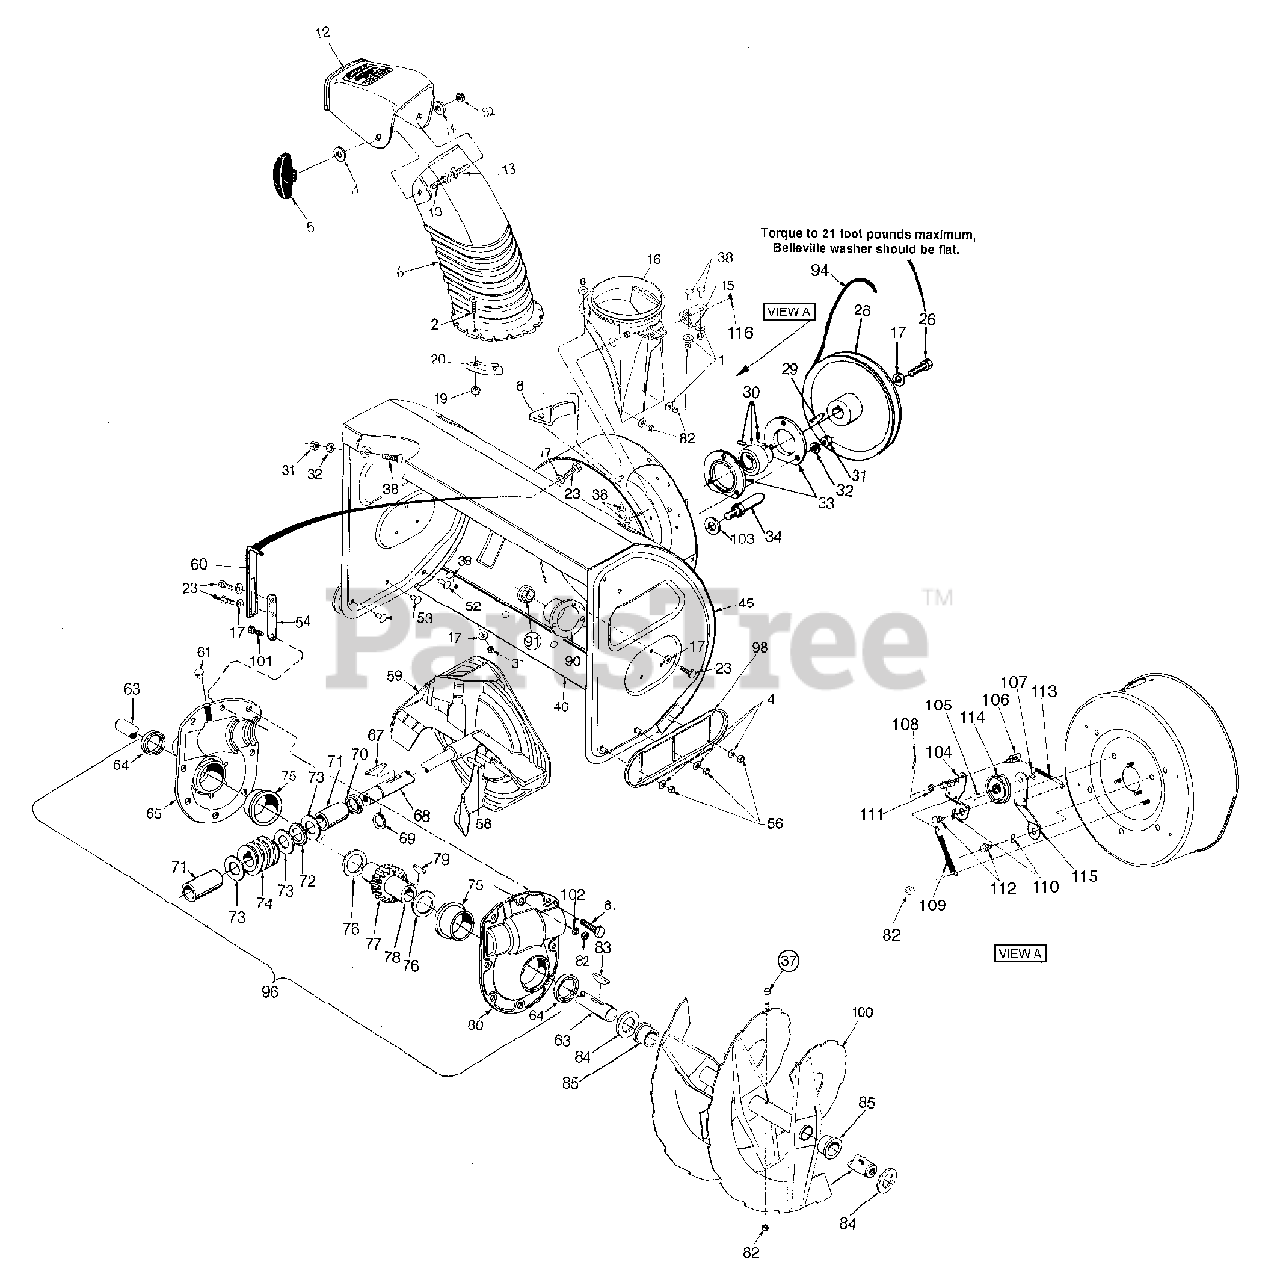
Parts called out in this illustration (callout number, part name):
1	Flat Washer .344 ID x .875 OD
2	Truss. Hd. Mach. Scr. 1/4-20 x .75
4	Belleville washer
5	Handle knob Ass'y
6	Extended lower black plastic chute 6" dia.
13	Carriage Bolt 5/16-18 x 1.00" Lg
14	Flat Washer .344 ID x .875 OD
16	Chute Adapter
17	Bell. Washer .345 ID x .88 OD x .06
19	Hex Cent. L-Nut 1/4-20 w/ Flange
20	Chute Flange Keeper
23	Hex Wash HD Self-Tap Scr 5.16-18 x .75
26	Hex Screw 5/16-18 x .75
28	1/2" V-Pulley .875 ID x 10.12 OD
29	#9 Hi-Pro Key 3/16 x 3/4 Dia HT
30	Self-Aligning Bearing .875 ID
31	Hex Nut 5.16-18 GD. 5
32	L-Wash 5.16 ID
33	Bearing Housing
34	Belt Keeper Studs 3/8-16 x 2.75
38	Carriage Bolt 5.16-18 x .75
52	Carriage Bolt 3/8-16 x 1.00 Gr. 5
53	Carriage Bolt 3/8-16 x .75" Lg.
56	Hex Jam Nut 3/8-16
58	Spring Spiral Pin Heavy - 5/16 dia x 1.7
61	Barbed Plug
63	Spiral Axle - 30"
64	Oil Seal 1.50 ID Garlock (76 x 6223)
65	Gear Housing Half - RH
67	#9 Hi-Pro Key 3/16 x 3/4 dia HT
68	Auger Drive Shaft
69	Snap Ring for .875 dia. shaft
70	Oil Seal for .875 ID Garlock (76 x 6133)
71	Sleeve Bearing .875 ID
72	Thrust Bearing .88 ID x 1.44 OD x .078
73	Flat Washer .88 ID x 1.4 OD x .125
74	Worm Gear LH Double Thread
75	Flange Brg. 1.5 ID x 1.75 OD x .80
76	Flat Washer 1.5 ID x 2.0 OD x .03
77	Worm Gear LH Double Thread (Bronze)
78	Worm Gear Shaft
79	#91 Woodruff Key 1/4 x 3/4 dia
80	Gear Housing Half LH
81	Hex Flange Scr. 5/16-18 x .75
82	Hex Ins. L-Nut 5/16-18
83	#91 Woodruff Key 1/4 x 3/4 dia
84	Flat Washer
85	Flange Bearing
91	Flange Bearing w/flats
94	V-Belt 1/2 x 44 LG
96	Worm Gear Box Ass'y
101	Hex Scr 5/16-18 x 1.25
102	5/16 Sprg Wash
103	3/8 Sprg Lock Wash
104	Brkt Ass'y; Brkt
105	Scr Hex Cap 3/8-24 x 1.5 GRD 5
106	Adjustment Ferrule
107	Hex Ins L-Nut 3/8-24
108	Intern Cot-Pin 5.16 dia
109	Spr Extn .470 dia x 4.75 Lg
110	Wave Washer .66 ID x .88 OD
111	Fl-Wash SAE .34 x .68 x .
112	Shld Scr .625 dia x .170 x .062
113	Rod Idler Auger
114	3.0 OD Flat Idler with Flanges
116	Plastic Bushing .380 ID
